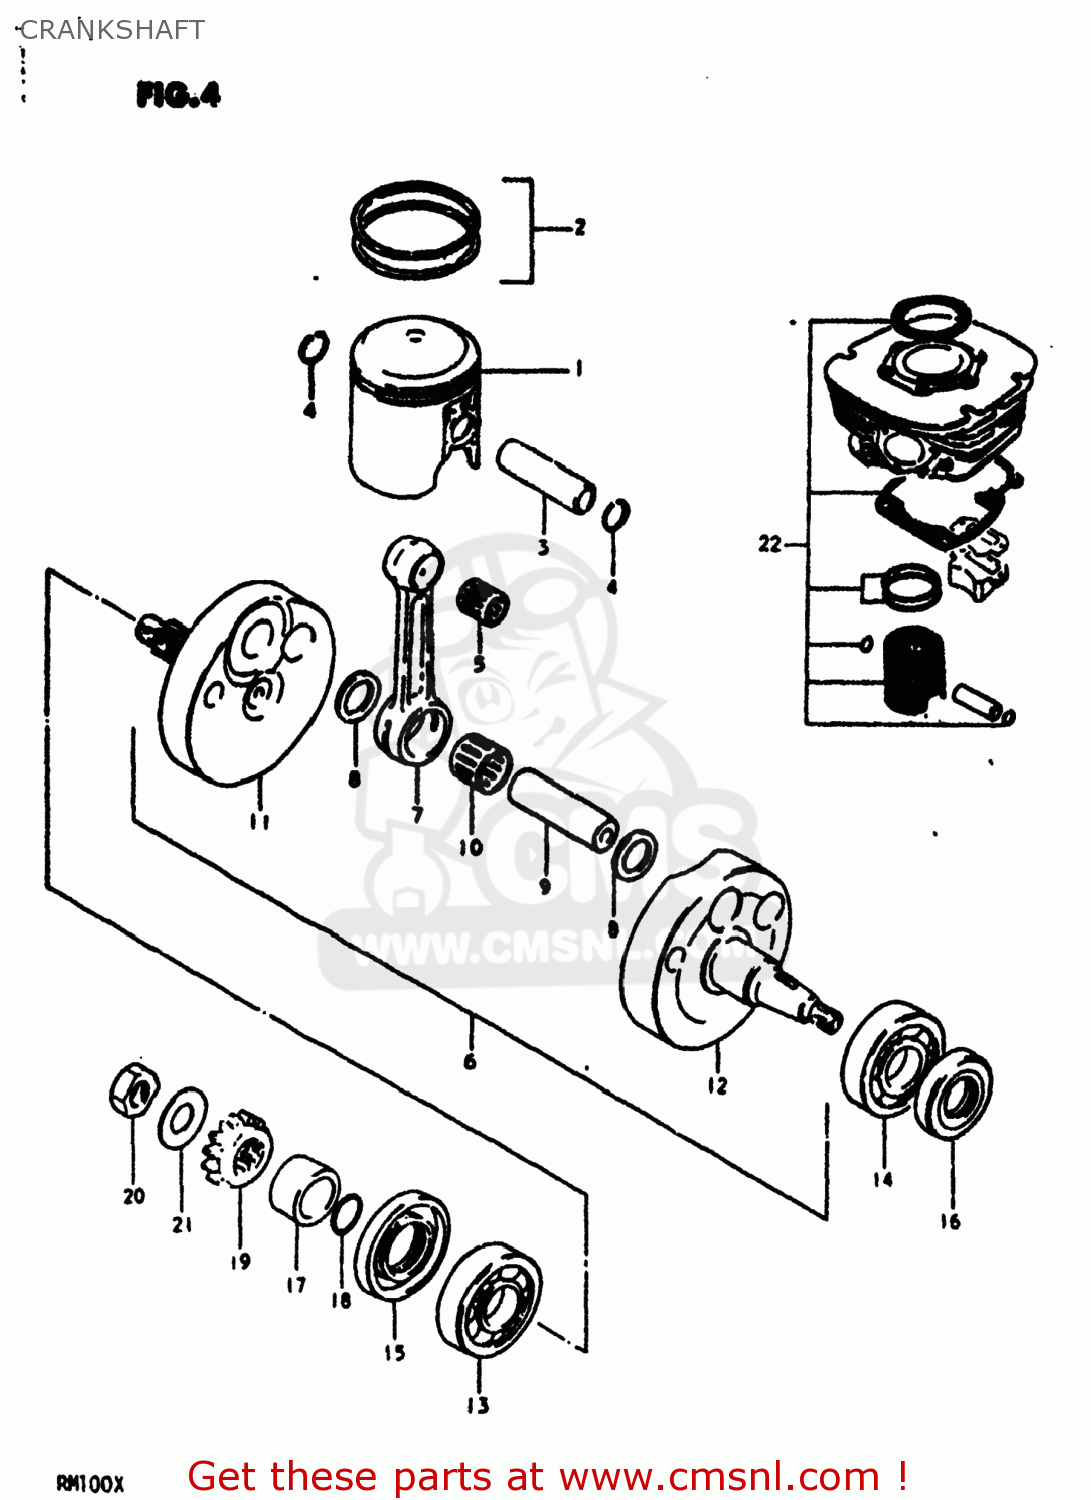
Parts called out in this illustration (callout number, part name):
1	PISTON (50.00MM)
2	RING SET,PISTON
3	PIN,PISTON 14MM
4	RING,SNAP 14MM
5	BEARING
6	CRANKSHAFT ASSEMBLY
7	CONNECTING ROD
8	WASHER(19X32X1)
9	PIN,CRANK
10	BEARING(19X25X16)
11	CRANKSHAFT
12	CRANKSHAFT,LEFT
13	BEARING
14	BEARING
15	SEAL,OIL(29X47X8)
16	OIL SEAL
17	SPACER (20X29X20.5)
18	O RING(D:2.4,ID:19.8)
19	GEAR,PRIMARY DRIVE
20	NUT
21	WASHER
22	PISTON SET
